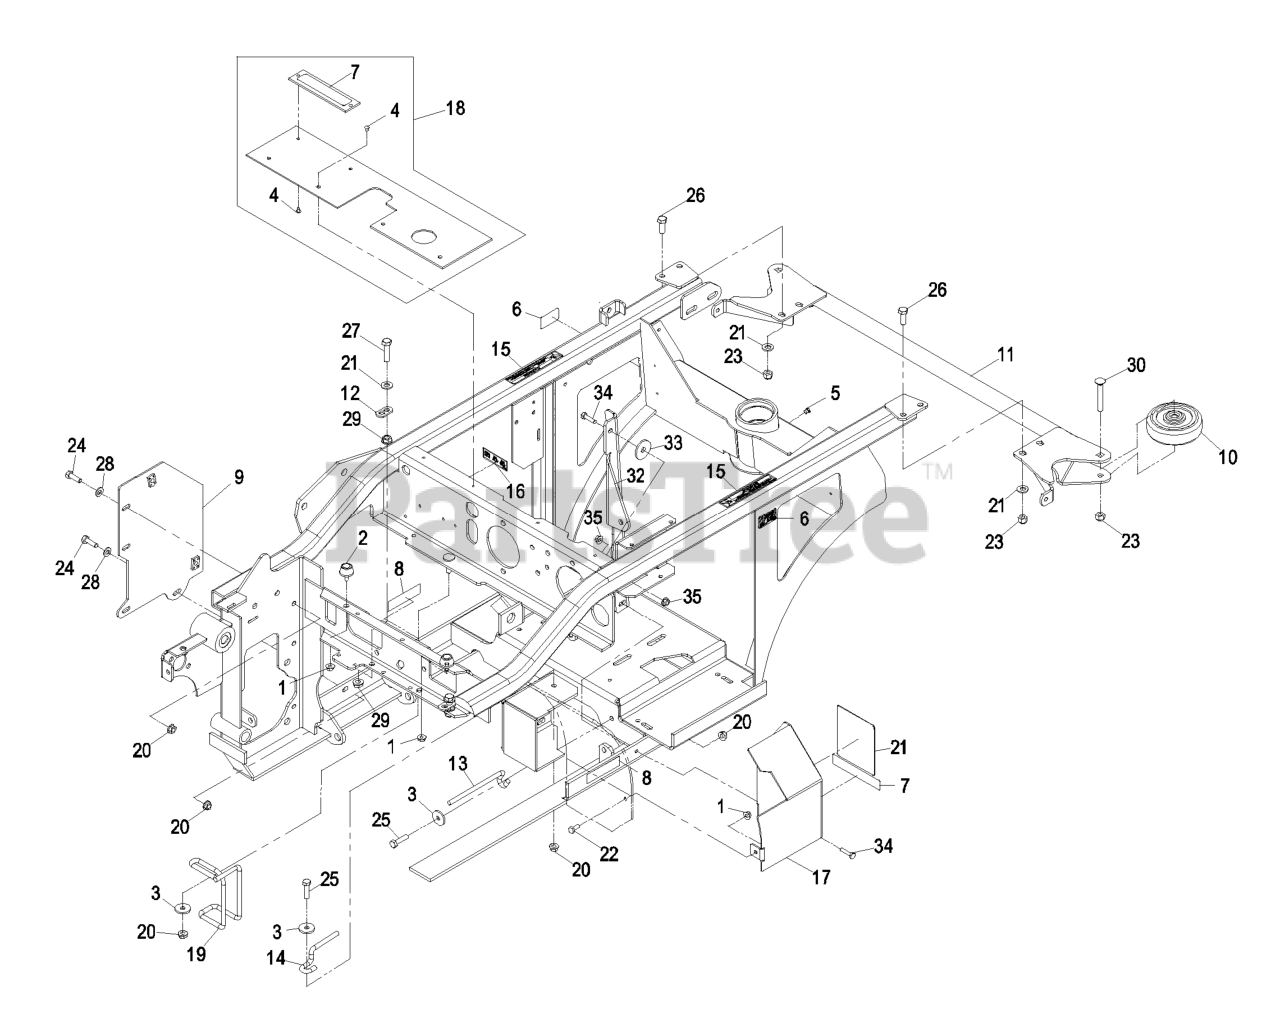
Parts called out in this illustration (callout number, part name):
2	BUMPER-RUBBER
4	RIVET-POP
6	DECAL-SURFACE, HOT
7	DECAL-WARNING
8	DECAL-COVER, MISSING
9	WLD,FENDER (RAW)
10	ROLLER-BUMPER
11	BUMPER-REAR
12	TAB,SPRING ANCHOR
13	GUIDE-BELT
14	GUIDE-BELT
15	DECAL,PINCH POINT
16	DECAL,RELAY
18	LIFT SHIELD ASM
19	GUIDE,BELT (PLATED)
21	DECAL,BELT ROUTING
22	SCREW-HH
23	NUT-LOCK, NI
24	SCREW-HH
25	SCREW-HH
26	SCREW-HH
27	SCREW-HH
28	WASHER-PLAIN
29	NUT-HHF, WHIZ
30	SCREW-CARR
31	WASHER-FLAT
32	BRACE-PTO
34	SCREW-HH
